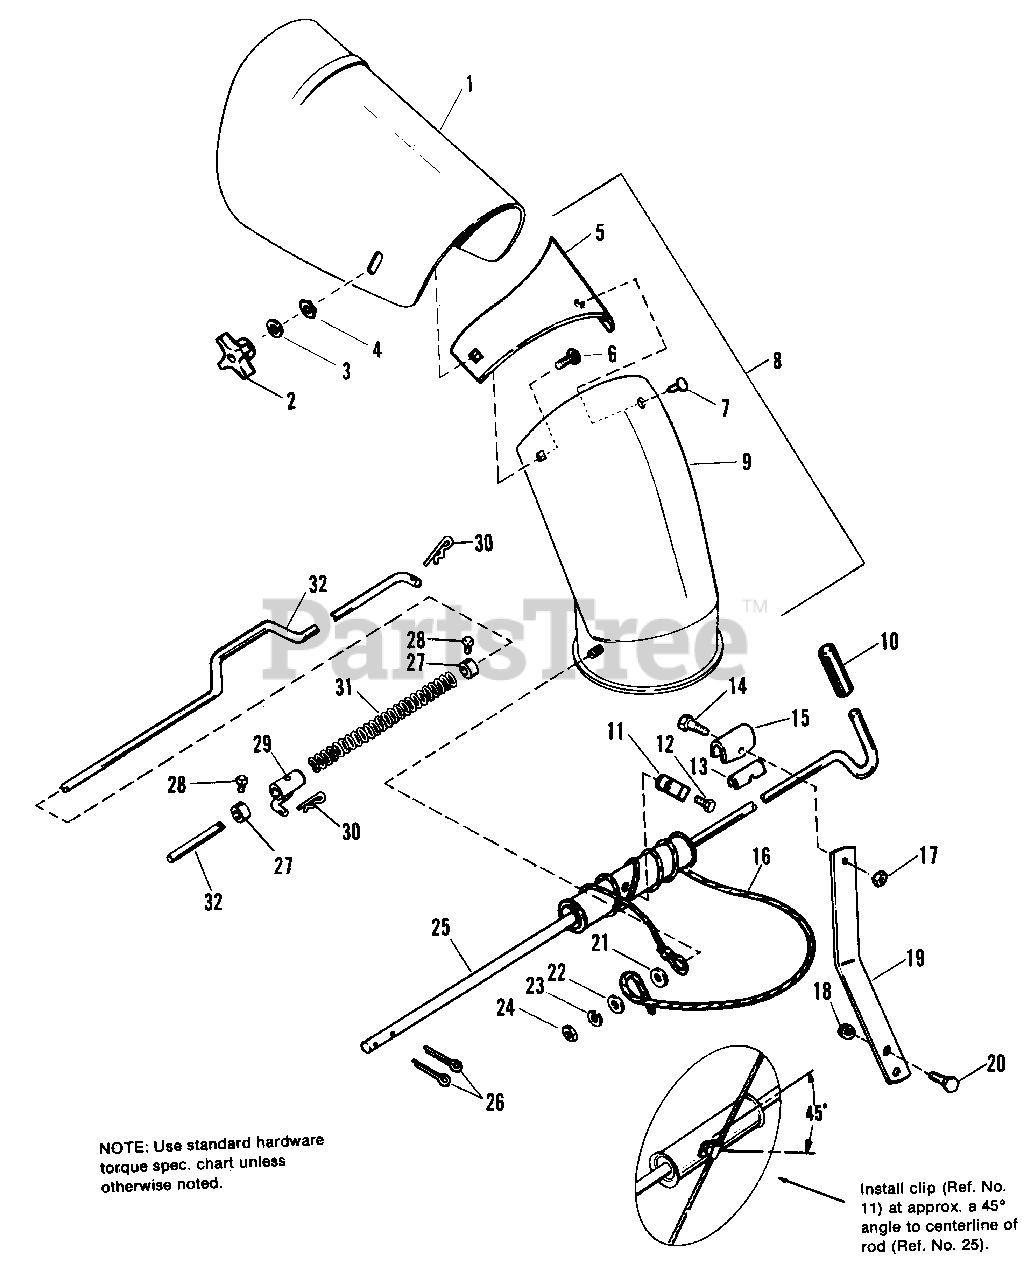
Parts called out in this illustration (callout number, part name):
1	EXTENSION, Spout
3	WASHER, Plain, 3/8
4	LOCKWASHER, Pyramidal, 3/8
5	DEFLECTOR, Snow
6	BOLT, Carriage, 5/16-18 x 3/4
8	SPOUT ASSY., Riveted
9	SPOUT ASSY.
10	GRIP, Handle
12	SCREW, Taptite, 1/4-20 x 3/8
13	GUIDE, Liner
14	CAPSCREW, Hex Hd., 5/16-18 x 1-1/4
16	CABLE ASSY.
17	LOCKNUT, 5/16-18
18	NUT, Flange, 3/8-16
19	ARM, Support
20	CAPSCREW, Hex Hd., 3/8-16 x 1
21	WASHER, Plain, 1/4
22	WASHER, Cup
23	LOCKWASHER, 5/16
24	NUT, Hex, 5/16-18
25	ROD ASSY., Spout Control
26	PIN, Cotter, 3/32 x 3/4
27	COLLAR
28	SETSCREW, 5/16-18 x 1/2
29	ROD GUIDE ASSY.
30	PIN, Clip
